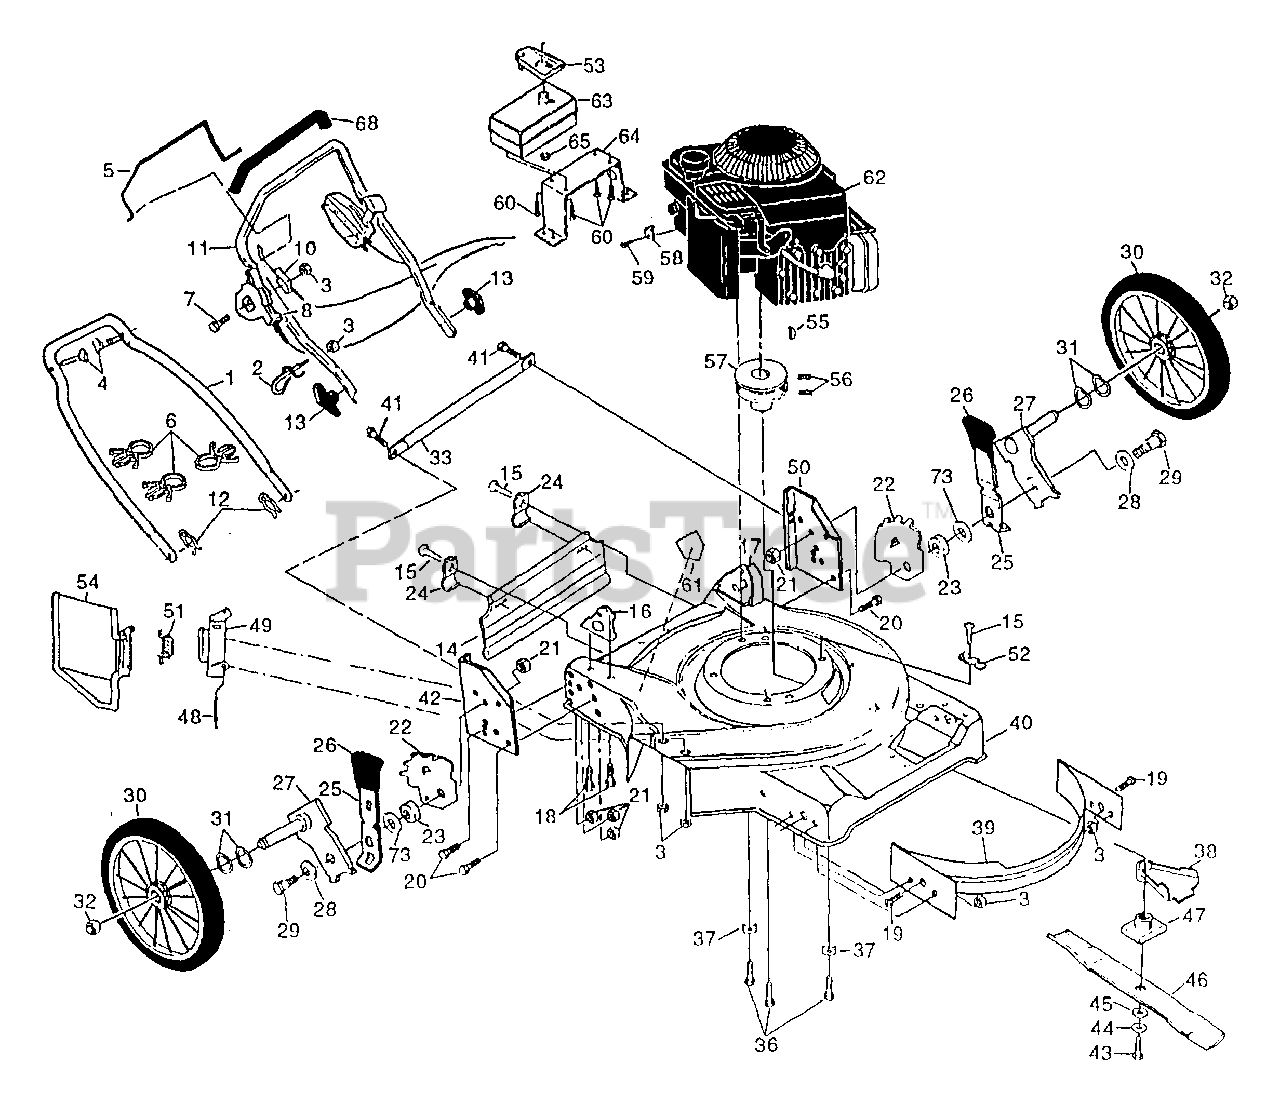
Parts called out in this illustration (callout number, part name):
1	Lower Handle (AYP part number)
2	Rope Guide
3	Locknut 1/4-20 (AYP part number)
4	Handle Bolt (AYP part number)
5	Control Bar (AYP part number)
6	Cable Clip (AYP part number)
7	Hex Washer Head Screw 1/4-20 x 2-1/8 (AYP part number)
8	Throttle Control
10	Engine Zone Cable
11	Upper Handle (AYP part number)
12	Hairpin Cotter (AYP part number)
13	Handle Knob (AYP part number)
14	Rear Skirt (AYP part number)
15	Hex Head Screw #10 (AYP part number)
16	Handle Bracket Assembly (Right) (AYP part number)
17	Handle Bracket Assembly (Left) (AYP part number)
18	Screw 5/16-18 x 3/4 (AYP part number)
19	Flat Machine Screw 1/4-20 x 3/4 (AYP part number)
20	Hex Head Bolt 3/8-16 x 3/4 (AYP part number)
21	Locknut (AYP part number)
22	Wheel Adjusting Bracket (R.R.) (AYP part number)
23	Spacer (AYP part number)
24	Skirt Bracket (AYP part number)
25	Selector Spring (AYP part number)
26	Selector Knob
27	Axle Arm Assembly (AYP part number)
28	Rear Spring Washer (AYP part number)
29	Shoulder Bolt 3/8-16 (AYP part number)
30	Wheel & Tire Assembly (Rear) (AYP part number)
31	Wave Washer (AYP part number)
32	Nut (AYP part number)
33	Rod Support (AYP part number)
35	Fuel Tank Cap (AYP part number)
36	Thread Rolling Screw 3/8-16 x 1 (AYP part number)
37	Engine Washer (AYP part number)
38	Debris Shield
39	Front Baffle
40	Mower Housing Kit
41	Screw (AYP part number)
42	Wheel Support Bracket R.H. (AYP part number)
43	Hex Head Screw 3/8-24 x 1-3/8 Gr. 8
44	Helical Washer 3/8 (AYP part number)
45	Hardened Washer (AYP part number)
46	22" Blade (AYP part number)
47	Blade Adapter
48	Hinge Rod (AYP part number)
49	Housing Bracket (AYP part number)
50	Wheel Support Bracket L.H. (AYP part number)
51	Torsion Spring (AYP part number)
52	Guide C(ip (AYP part number)
53	Deflector (AYP part number)
54	Discharge Guard (AYP part number)
55	Hi-Pro Key (AYP part number)
56	Set Screw (AYP part number)
57	Engine Pulley (AYP part number)
58	Cable Clamp (AYP part number)
59	Screw #10 x 5/8 (AYP part number)
61	Danger Decal (AYP part number)
62	Engine - Briggs & Stratton
63	Fuel Tank (AYP part number)
64	Fuel Tank Bracket (AYP part number)
65	Fuel Line Clamp (AYP part number)
68	Handle Grip (AYP part number)
73	Flat Washer 3/8 (AYP part number)
